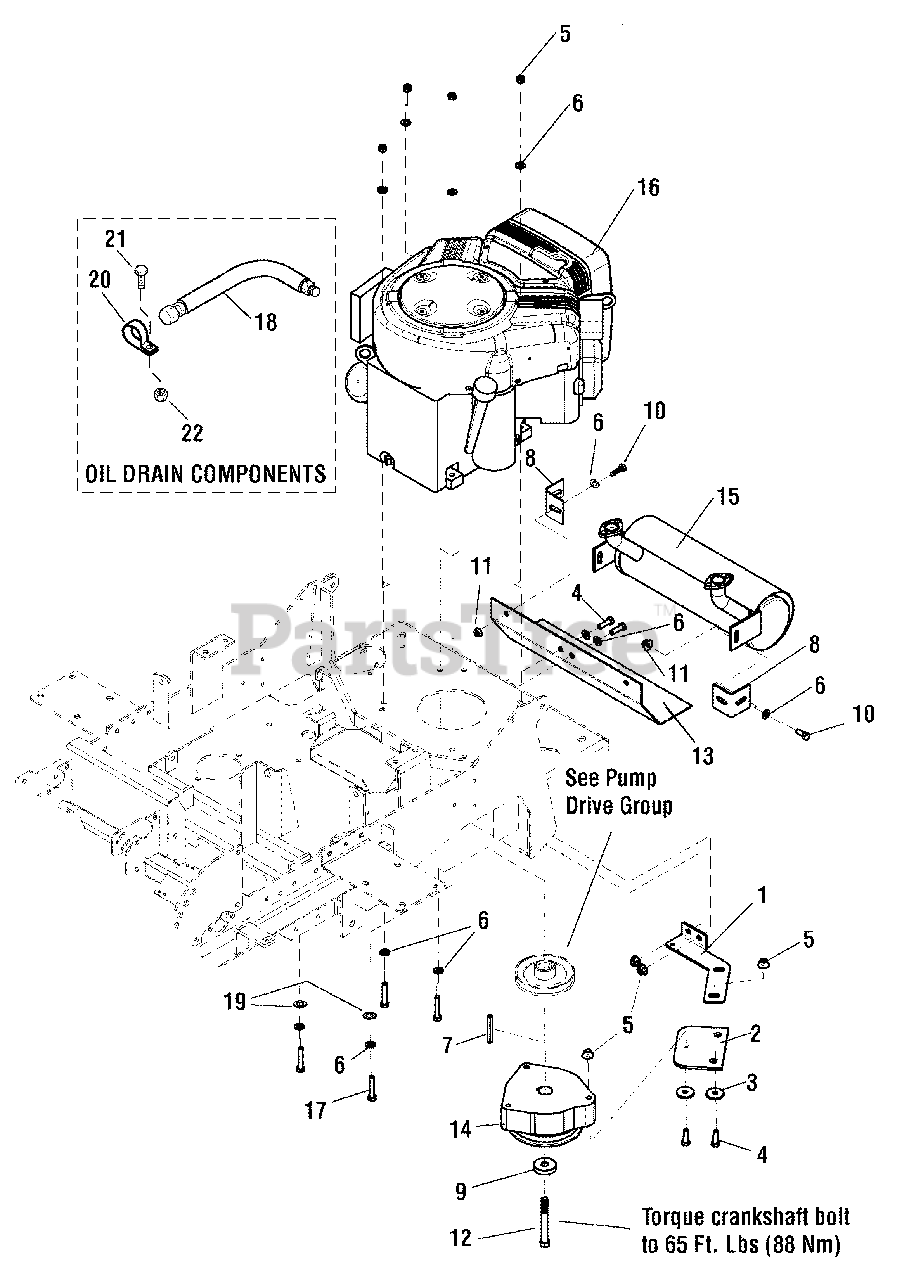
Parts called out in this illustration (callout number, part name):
1	PLATE, CLUTCH ANCHOR
2	CLUTCH ANCHOR PAD
3	WASHER, .34 X 1.25 X 10 GA
4	BOLT, 5/16-18 X 1" GD5 YZ
5	NUT, 5/16-18 HEX NYLOCK FLANGE
6	WASHER, 5/16" SAE
7	KEY, 1/4" SQ. X 2 1/4
8	BRACKET,SUPPORT,MUFFLER
9	SPACER, .45 X 1.62 X .37
10	BOLT, 5/16-18 X 3/4" GRD5
11	NUT, 5/16-18 HEX LG SERR FLG.
12	BOLT, CRANKSHAFT, 7/16-20 X 3-1/4"
13	PLATE, HEAT SHIELD - ORG
14	CLUTCH, # 51110100,ELECTRIC, 1" SHAFT
15	MUFFLER, ACS
16	* ENGINE, BRIGGS VANGUARD
17	BOLT, 5/16-18 X 2-1/4" GD5 YZ
18	HOSE, OIL DRAIN
19	WASHER, 5/16" INT. TOOTH LOCK
20	CLAMP, VINYL INSULATED
21	BOLT, 1/4-20 X 3/4" GD5 YZ
22	NUT, 1/4-20 HEX SERR. FLANGE
